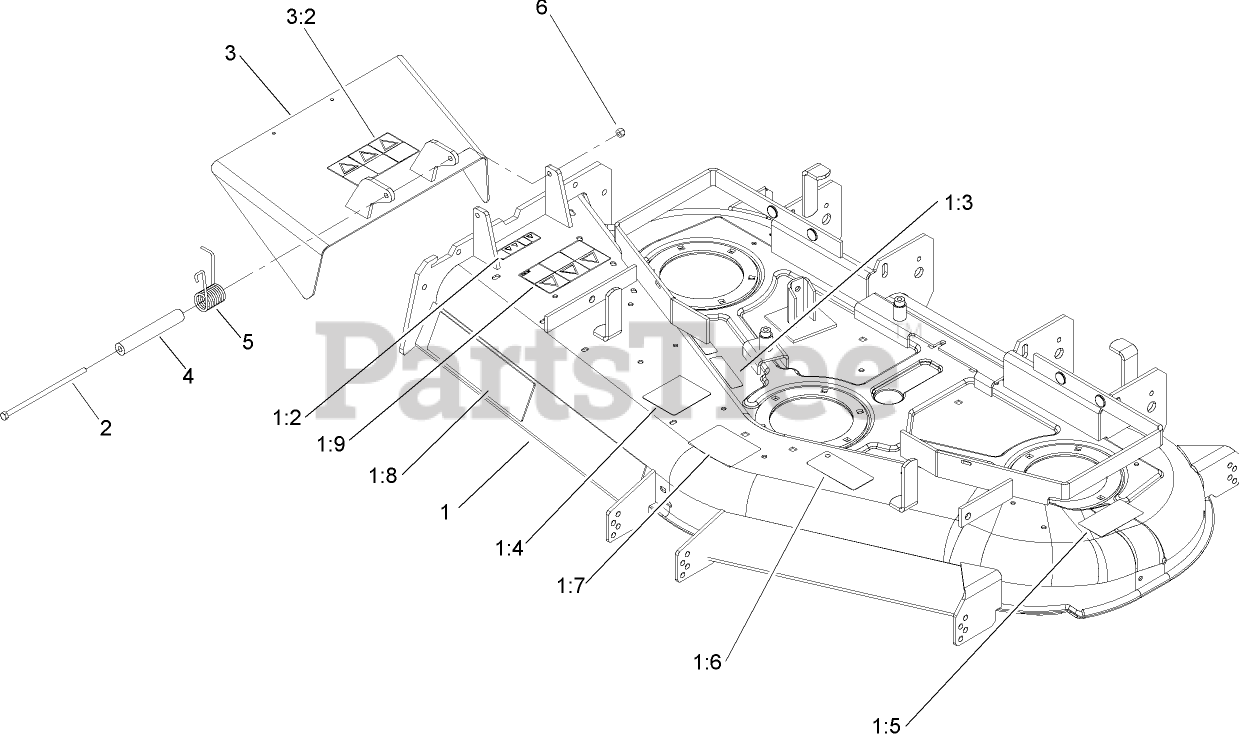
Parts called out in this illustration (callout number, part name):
1	DECK ASM
1:2	DECAL-WARNING, DEFLECTOR
1:3	DECAL-WARNING
1:4	DECAL-ROUTING, BELT
1:5	DECAL-DANGER
1:6	DECAL-TORQUE, BLADE BOLT
1:7	DECAL-ANTI SCALP
1:9	DECAL-DANGER
2	SCREW-HH
3	DEFLECTOR ASM
3:2	DECAL-DANGER
4	SPACER
5	SPRING-TORSION
6	NUT-LOCK, NI
